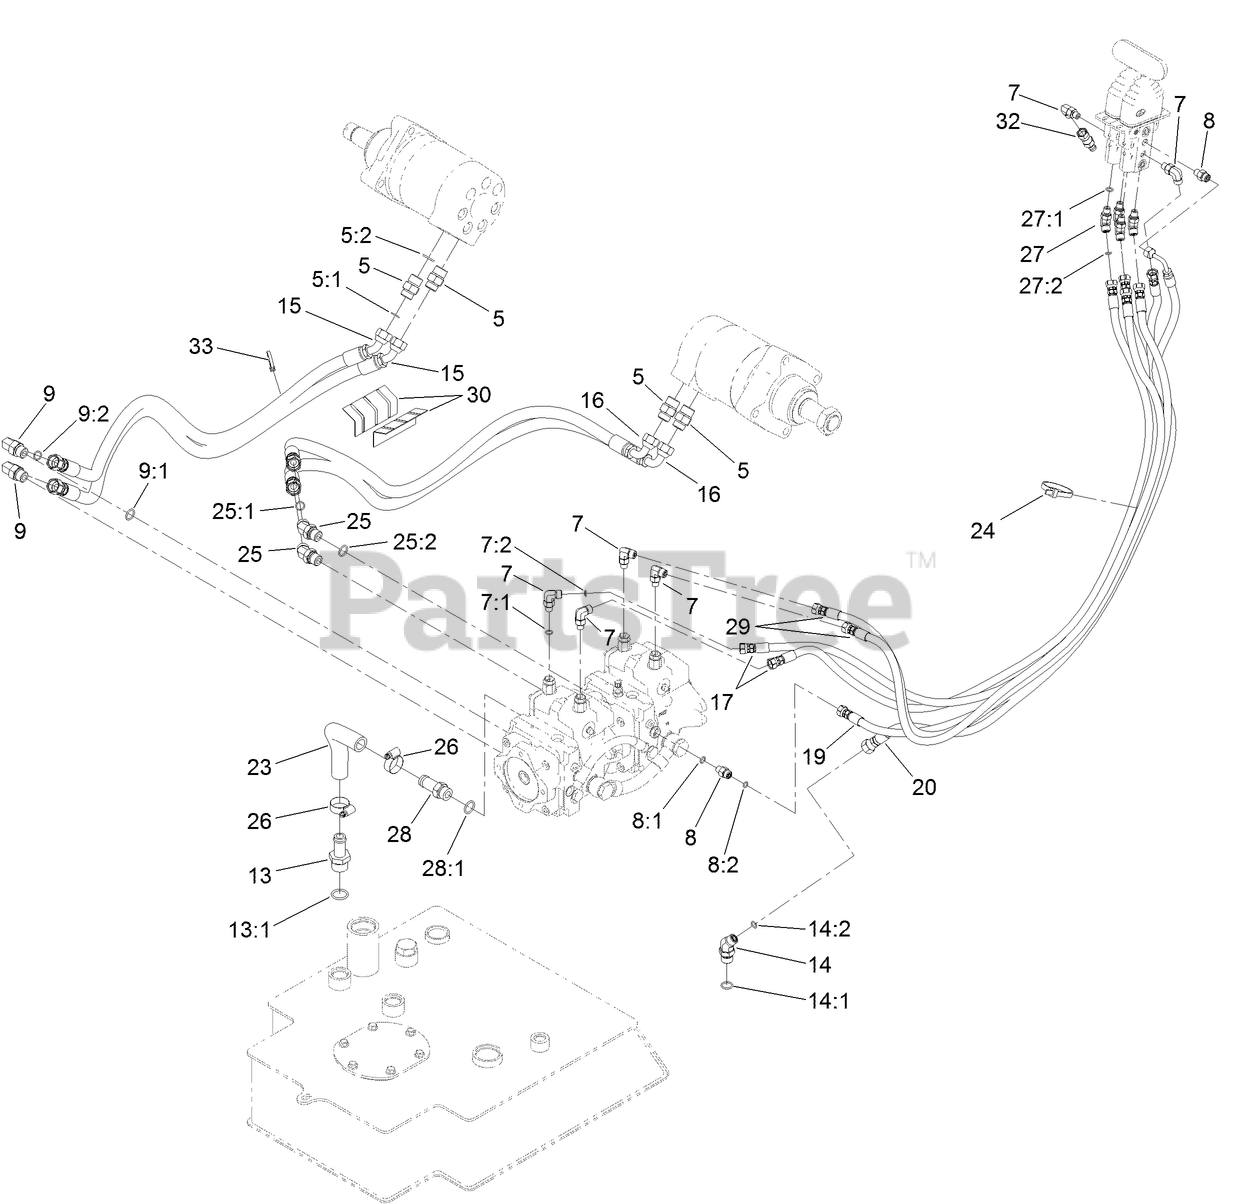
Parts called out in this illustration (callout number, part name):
5	FITTING-STRAIGHT
5:1	O-RING
5:2	O-RING
7	FITTING-ELBOW, 90 DEG
7:1	O-RING
7:2	O-RING
8	FITTING-STRAIGHT
8:1	O-RING
8:2	O-RING
9	FITTING-ELBOW, 90 DEG
9:1	O-RING
9:2	O-RING
13	FITTING
13:1	O-RING
14	FITTING-HYD, 45 DEG
14:1	O-RING
14:2	O-RING
15	HOSE-HYD
16	HOSE-HYD
17	HOSE-HYD
19	HOSE-HYD
20	HOSE-RETURN
23	HOSE-RETURN
24	TIE-CABLE
25	FITTING-HYD, 45 DEG
25:1	O-RING
25:2	O-RING
26	CLAMP-HOSE
27	FITTING-HYD, 45 DEG
27:1	O-RING
27:2	O-RING
28	FITTING-STR
28:1	O-RING
29	HOSE-HYD
30	PROTECTOR-HOSE
32	NIPPLE-TEST
33	TIE-CABLE
